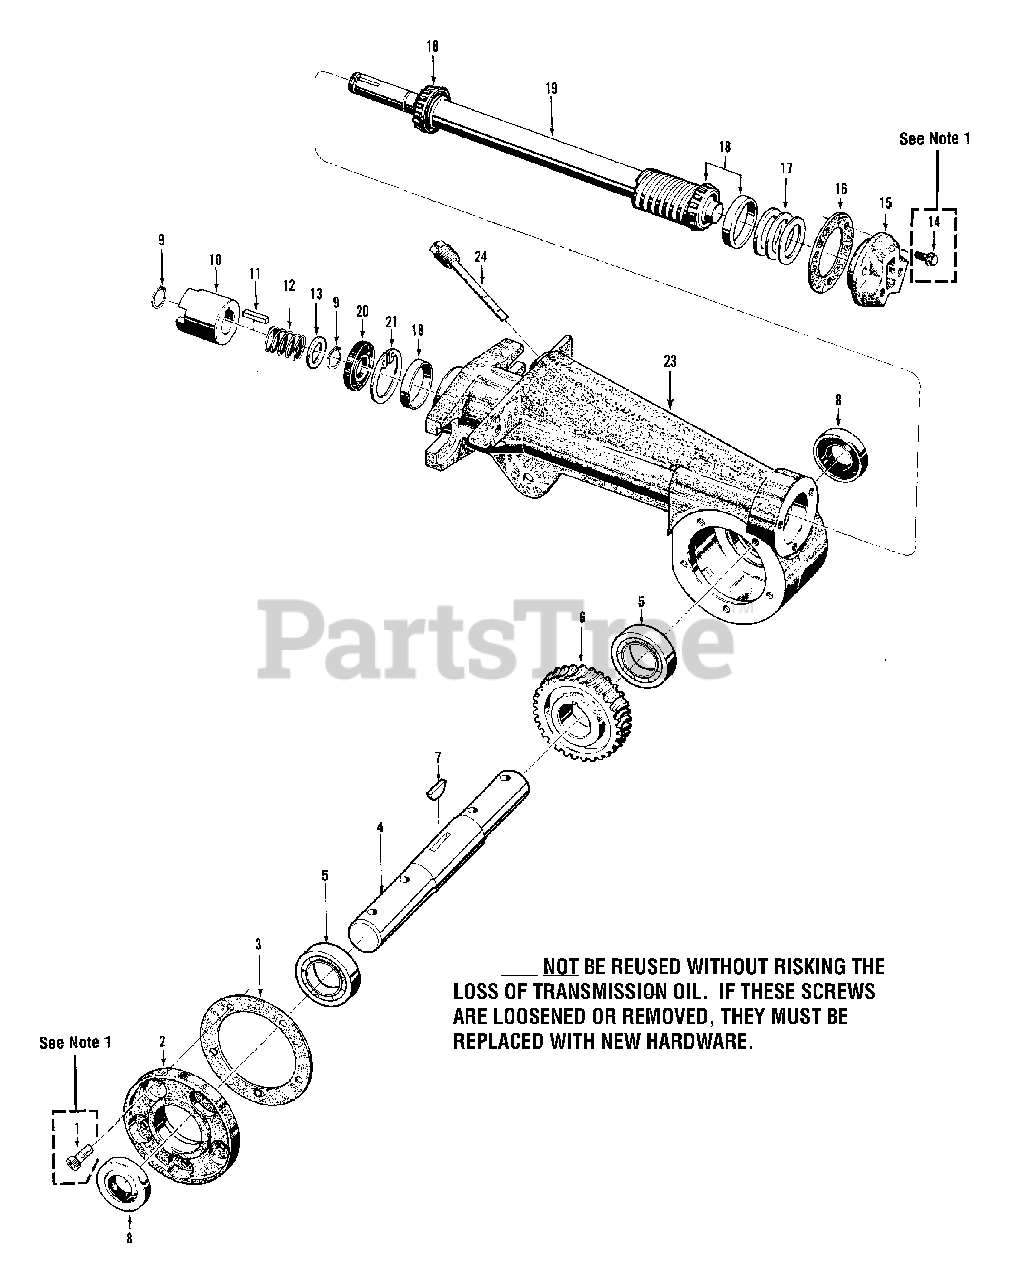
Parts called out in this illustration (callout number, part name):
1	Screw-self-sealing,1/4"-20 x 5/8"
2	Cover-tiller housing
3	Gasket-tiller housing cover, .010" thick
3	Gasket-same as above, .030" thick
4	Shaft-tiller tine
5	Ball Bearing
6	Worm Gear-bronze, tiller tine shaft
7	Key-tiller tine shaft, woodruff key
8	Seal-oil, tiller tine shaft
9	Retaining Ring-external
10	Dog Clutch-tiller drive shaft
11	Key-3/16" x 1"
12	Spring-dog clutch
13	Shim-dog clutch, 1/16"(.62") thick
14	Screw-self-sealing,1/4"-20 x 7/8"
15	Cap-rear bearing
16	Gasket-rear bearing cap
17	Shim-front bearing cap, .010" thick
17	Shim-same as above, .030" thick
17	Shim-same as above, .005" thick
17	Shim-same as above, .062" thick
18	Bearing & Race
19	Shaft-main tiller drive
20	Seal-oil, drive shaft, front
21	Retaining Ring-internal
23	Housing-tiller attachment
24	Dipstick-oil, tiller attachment
